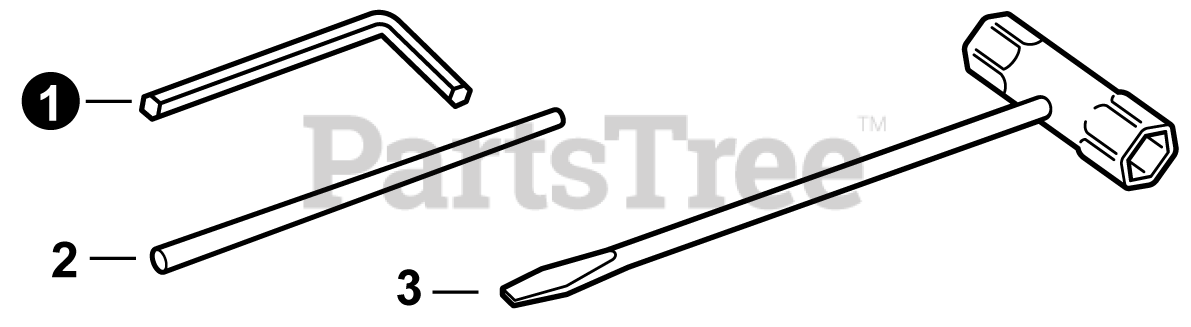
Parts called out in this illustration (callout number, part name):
1	WRENCH, ALLEN
2	TOOL, LOCKING 5×120 MM
3	T-WRENCH 17×19 L200
